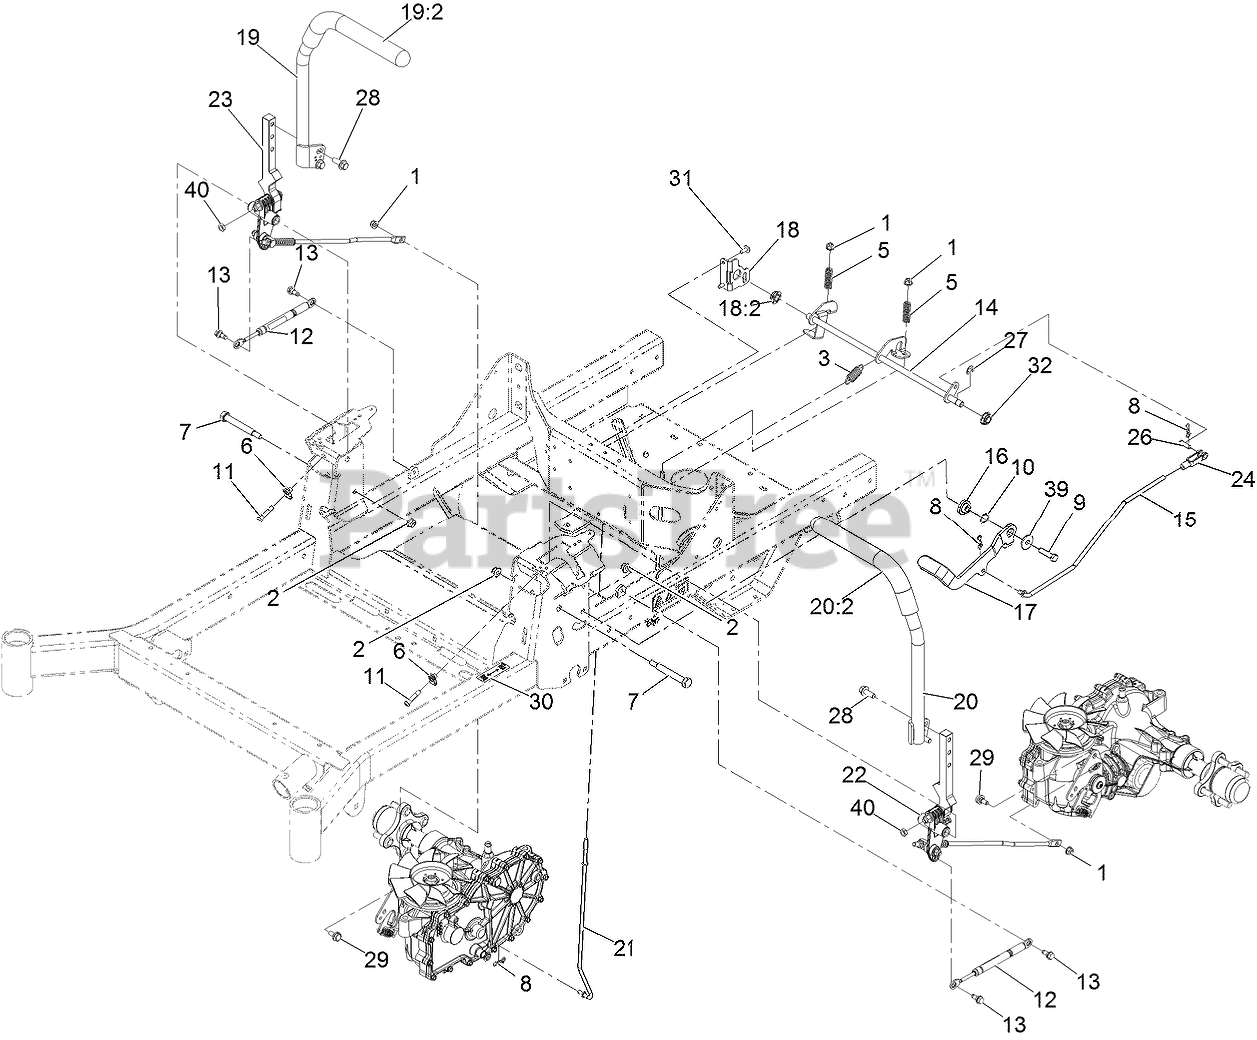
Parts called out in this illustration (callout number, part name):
1	NUT-HF, NI
2	NUT-HF, NI
3	SPRING-EXTENSION
5	SPRING-COMPRESSION
7	BOLT-PIVOT
8	PIN-COTTER, LOCKING
9	SCREW-HH
10	WASHER-WAVE
11	SCREW-HSBH
13	SCREW-SHOULDER
14	SHAFT-BRAKE
15	LINKAGE-BRAKE, UPPER
16	PIVOT-FLANGE
17	LEVER-BRAKE (WITH GRIP)
18	BRACKET-BRAKE
18:2	BEARING-SPHERICAL
19	RH EXTENDED CONTROL HANDL
20	LH EXTENDED CONTROL HANDL
21	LINKAGE-BRAKE, LOWER
22	LH Motion Control ASM
23	RH Motion Control ASM
24	YOKE-ADJUSTABLE
26	PIN-CLEVIS
27	RING-RETAINING, EXTERNAL
28	SCREW-HHF 3/8-16 X 1
29	BOLT-SHOULDER,HFH
30	DECAL-BRAKE, PARKING
31	SCREW-TORX
32	BEARING-SPHERICAL
39	WASHER
40	NUT-JAM
